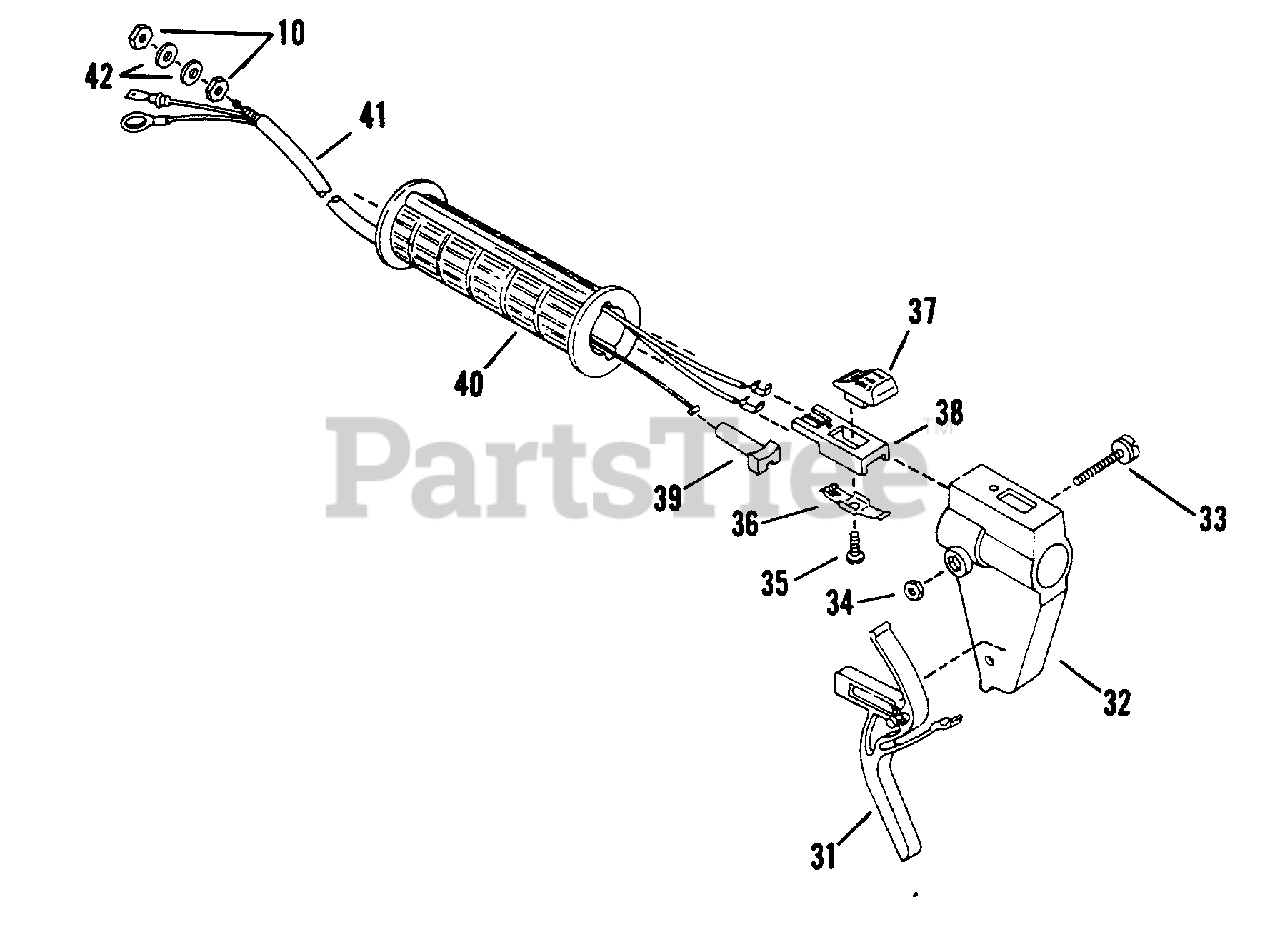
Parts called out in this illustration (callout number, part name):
10	NUT, #M6 Hex
31	TRIGGER, Throttle
32	HOUSING, Trigger
33	SCREW, Sems, M5 x 28 5mm P.H.
34	NUT, M5 Hex
35	SCREW, #8-18 x.1/2" P.H.
36	CONTACT SWITCH
37	BUTTON-STOP SWITCH
38	BASE-STOP SWITCH
41	HARNESS-WIRE ASSM'Y
